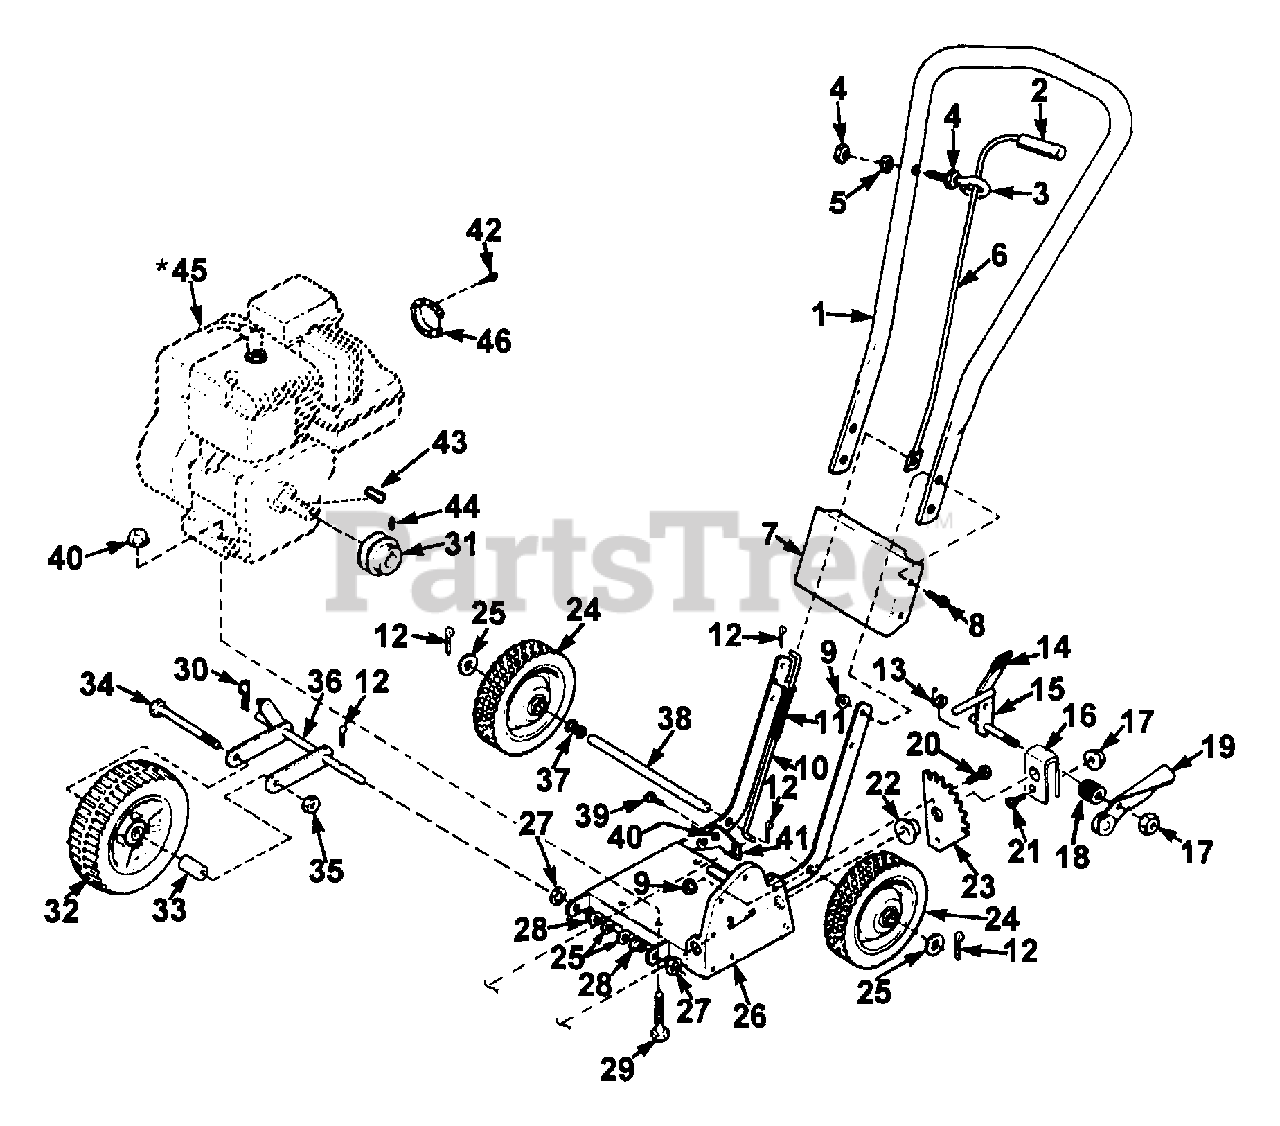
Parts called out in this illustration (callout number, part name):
2	Grip (Depth Control)
4	Nut (1/4-20)
5	Washer (lock 1/4")
6	Control (Depth)
7	Cover (W/ Decal)
8	Screw (Sems 1/4-20 x 1")
9	Nut (1/4-20)
10	Rod (Lower Depth)
11	Spring (Depth Control)
12	Cotter Pin
13	Spring (Angle Adjuster)
14	Grip (Angle Adjuster)
15	Lever (Angle Adjusting)
16	Clamp (Angle Adjuster)
17	Nut (Hex Locking)
18	Bushing (Adjuster)
19	Lever (Clutch)
20	Screw (Sems Hex Head)
21	Screw (3/8-16 x 1 1/4)
22	Bushing (Nylon 3/4)
23	Comb (Angle Adjuster)
24	Wheel & Tire
25	Washer (Flat)
26	Frame (Main)
27	Retainer (Bushing)
28	Bushing (Nylon)
29	Screw (Hex Cap)
30	Pin (Cotter)
31	Pulley (Engine)
32	Wheel (Front)
33	Spacer (Axle)
34	Screw (1/2-13 x 4")
35	Nut (Hex Locking)
36	Bracket (F. Wheel)
37	Spring (Axle)
38	Axle (Rear)
39	Screw (Hex Head)
40	Nut (Flange 5/16-18)
41	Bracket (Depth)
42	Screw (Hex Head)
43	Key
44	Screw (Set)
45	Engine
46	Deflector
